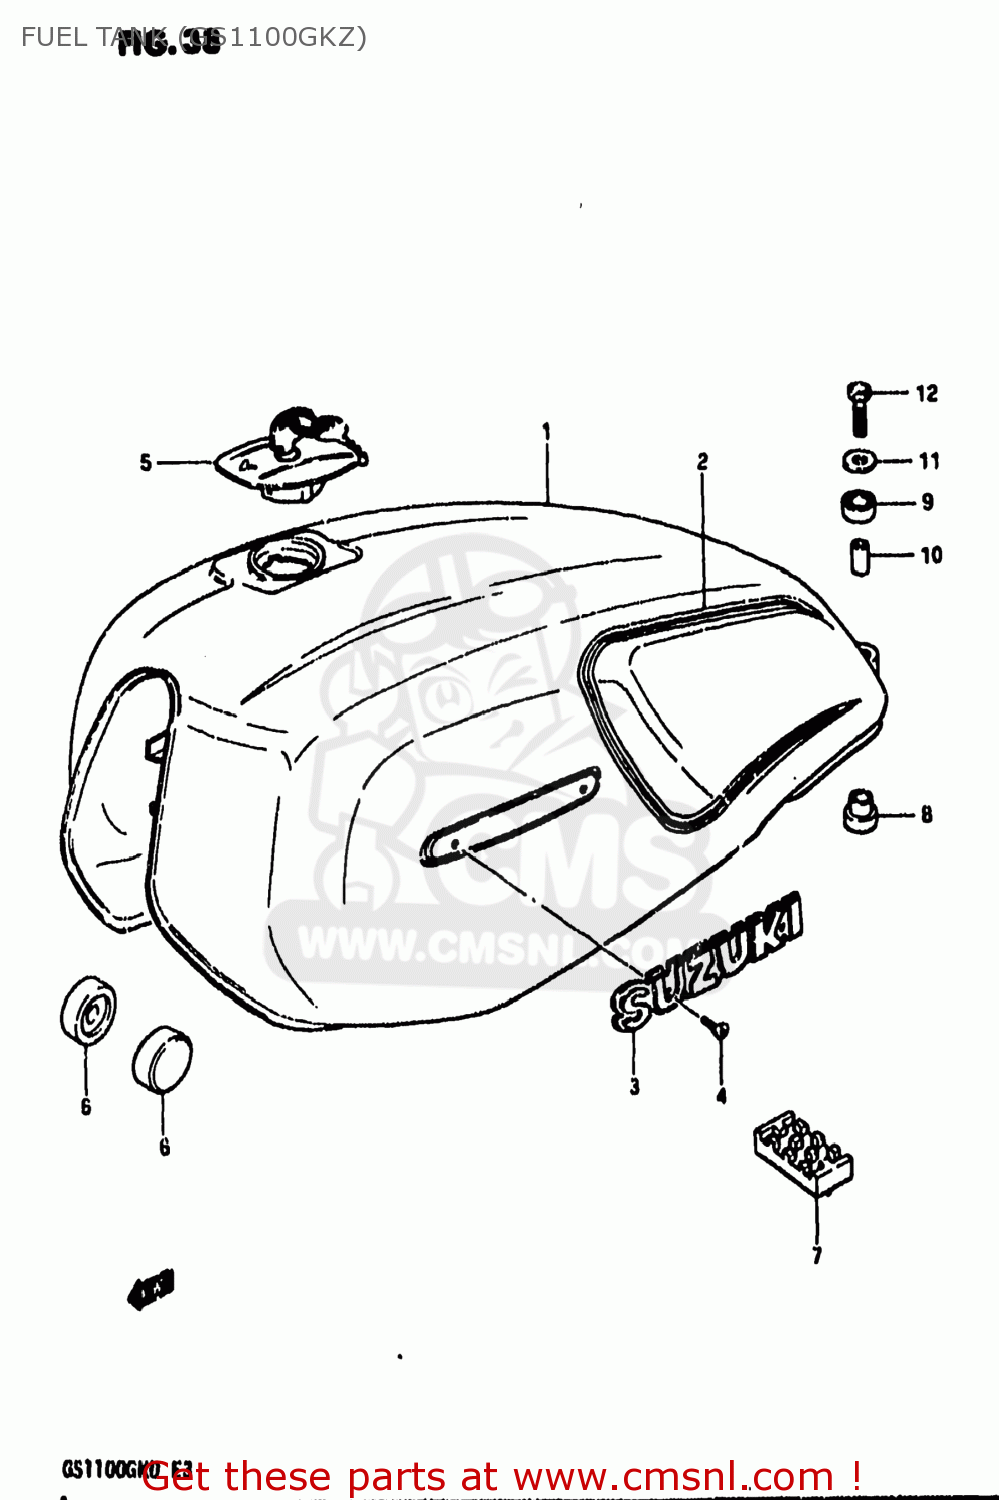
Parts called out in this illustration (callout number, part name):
1	TANK ASSEMBLY,FUEL
2	TAPE SET,FUEL TANK
3	EMBLEM
4	SCREW 3X6
5	CAP SET,FUEL TANK
6	CUSHION
7	CUSHION,FUEL TANK
8	CUSHION
9	CUSHION
10	SPACER (6.4X9X21.5)
11	WASHER (6.5X24X1.6)
12	BOLT
